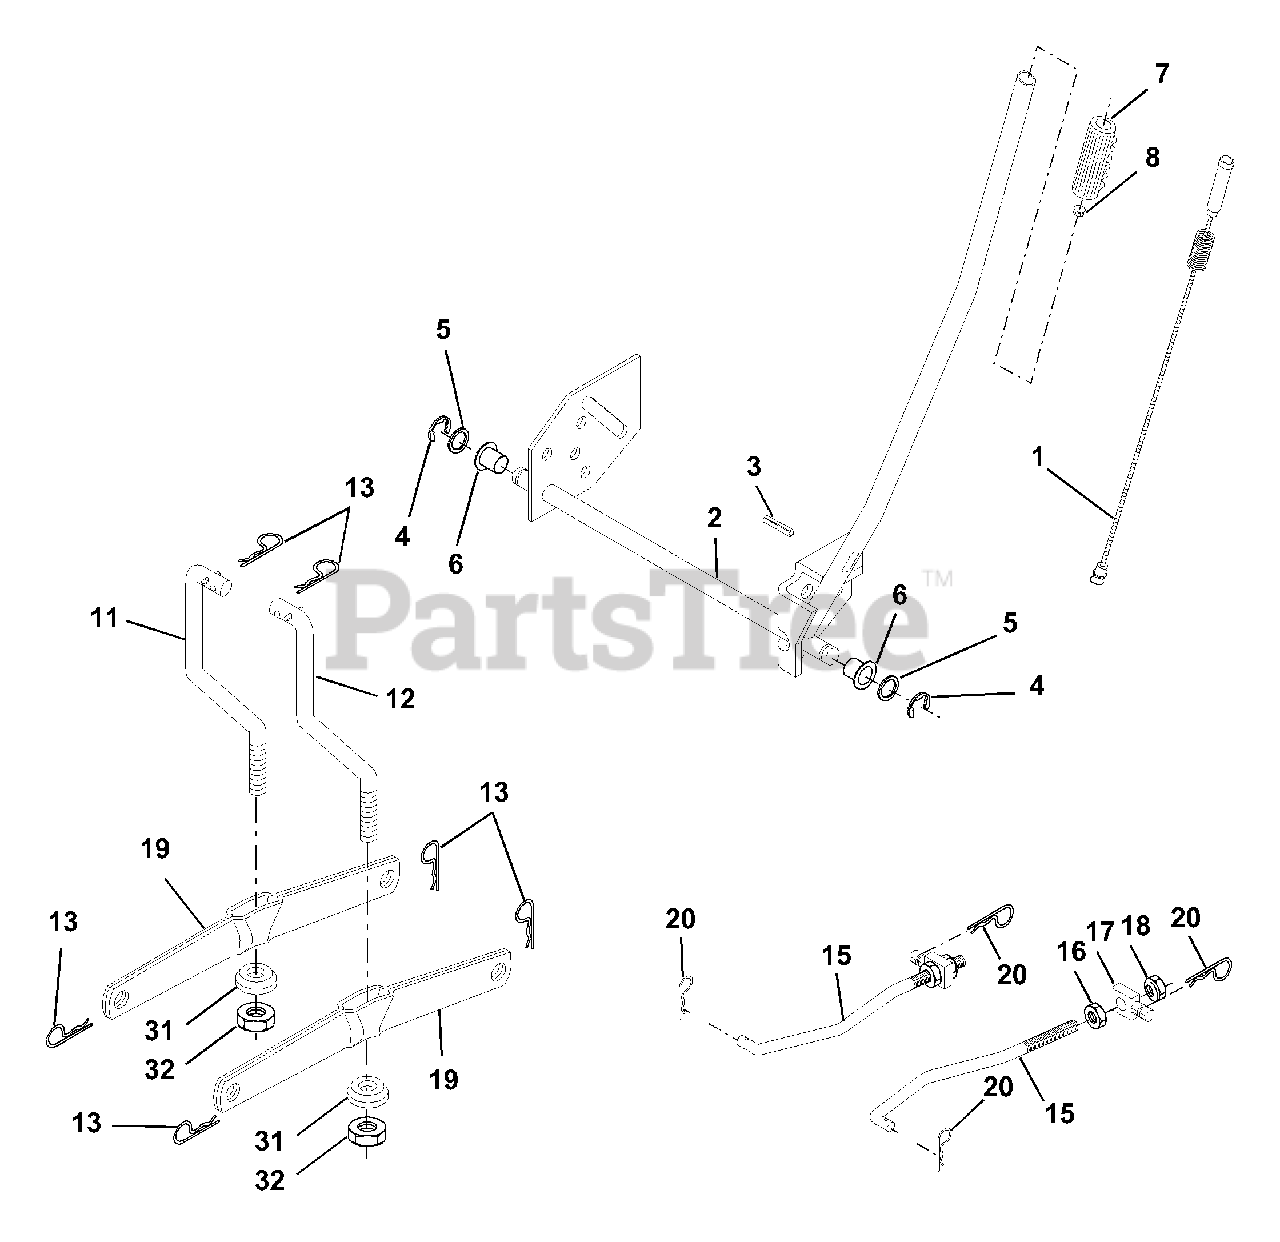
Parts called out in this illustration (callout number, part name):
1	Wire Asm Inner/Sprg w/plunger
2	Shaft Asm Lift RH
3	Pin Groove 1 500 Zinc
4	E Ring #5133-62
5	Washer 21/32 X 1 X 21 Ga
6	Bearing Nylon Blk 629 Id
7	Grip Handle Bicycle Matte Blk
8	Button Plunger Black
11	Link Lift LH Fixed Length
12	Link Lift RH Fixed Length
13	Retainer Spring
15	Link Front
16	Nut Jam Hex 1/2-13 Unc
17	Trunnion Blk Zinc
18	Nut Lockw/Wsh 1/2-13 Unc
19	Arm Suspension Rear
20	Retainer, Spring
31	Bearing Pvt Lift Spherical
32	Nut Crownlock 3/8-24
